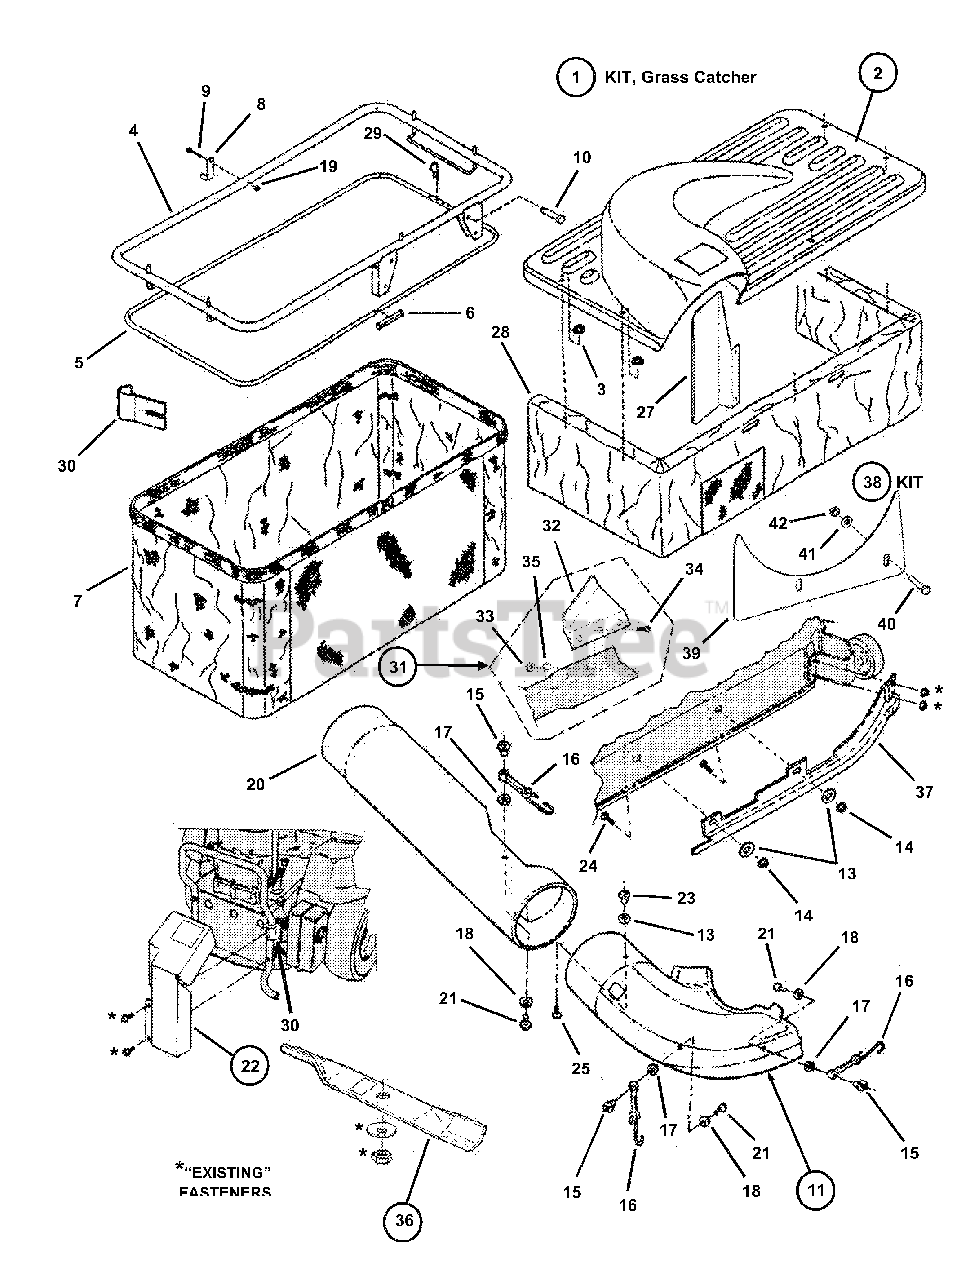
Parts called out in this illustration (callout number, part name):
1	KIT, Grass Catcher (38" Models)
2	TOP, Container
3	WASHER, 5/16" Faceted
4	FRAME, Weldment
5	ROD, Bag
6	CONNECTOR, Bag Rod
7	BAG, Grass
8	LATCH, Top
9	SCREW, #10-32 x 1-3/8" Hex Head Machine
10	PIN, 5/16 x 1-11/16" Clevis
11	ADAPTER, Deck
13	WASHER, 11/32" Flat
14	NUT, 5/16-18 Hex Center Lock
15	NUT, #10-24 x 5/8" Weld
16	STRAP, Mounting Bag Adapter/Tube
17	WASHER, 3/16" Flat
18	WASHER, 7/32" Flat
19	NUT, #10-32 Hex Nyloc
20	TUBE, Grass (37" long)
21	SCREW, #10-24 x 5/8" Pan Head
22	ASSEMBLY, Debris Shield
23	TEENUT, 5/16-18
24	SCREW, 5/16-18 x 3/4" Hex Head Cap, Grade 5
25	SCREW, 5/16-18 x 5/8" Cross Recess Pan Head
27	SHIELD, Muffler Heat (8 HP Engines)
28	DUST SKIRT
29	PIN, 3/32 x 1-1/2" Hair
30	REINFORCEMENT, Bumper
31	KIT, Air Lift
32	AIR LIFT
33	NUT, 5/16-24 Hex
34	SCREW, 5/16-24 x 11/16" Oval Head Machine
35	WASHER, 5/16" Internal Tooth Lock
36	ASSEMBLY, High Lift Blade & Decal (Decal No. 44686)(blade length: 19.64; hole diameter: .981")
37	BAFFLE, 38" Deck MY97
38	KIT, Catcher Debris Shield
39	SHIELD, Debris
40	BOLT, 1/4-20 x 1-1/2" Hex
41	WASHER, 1/4" Flat
42	NUT, 1/4-20 Hex Top Lock
